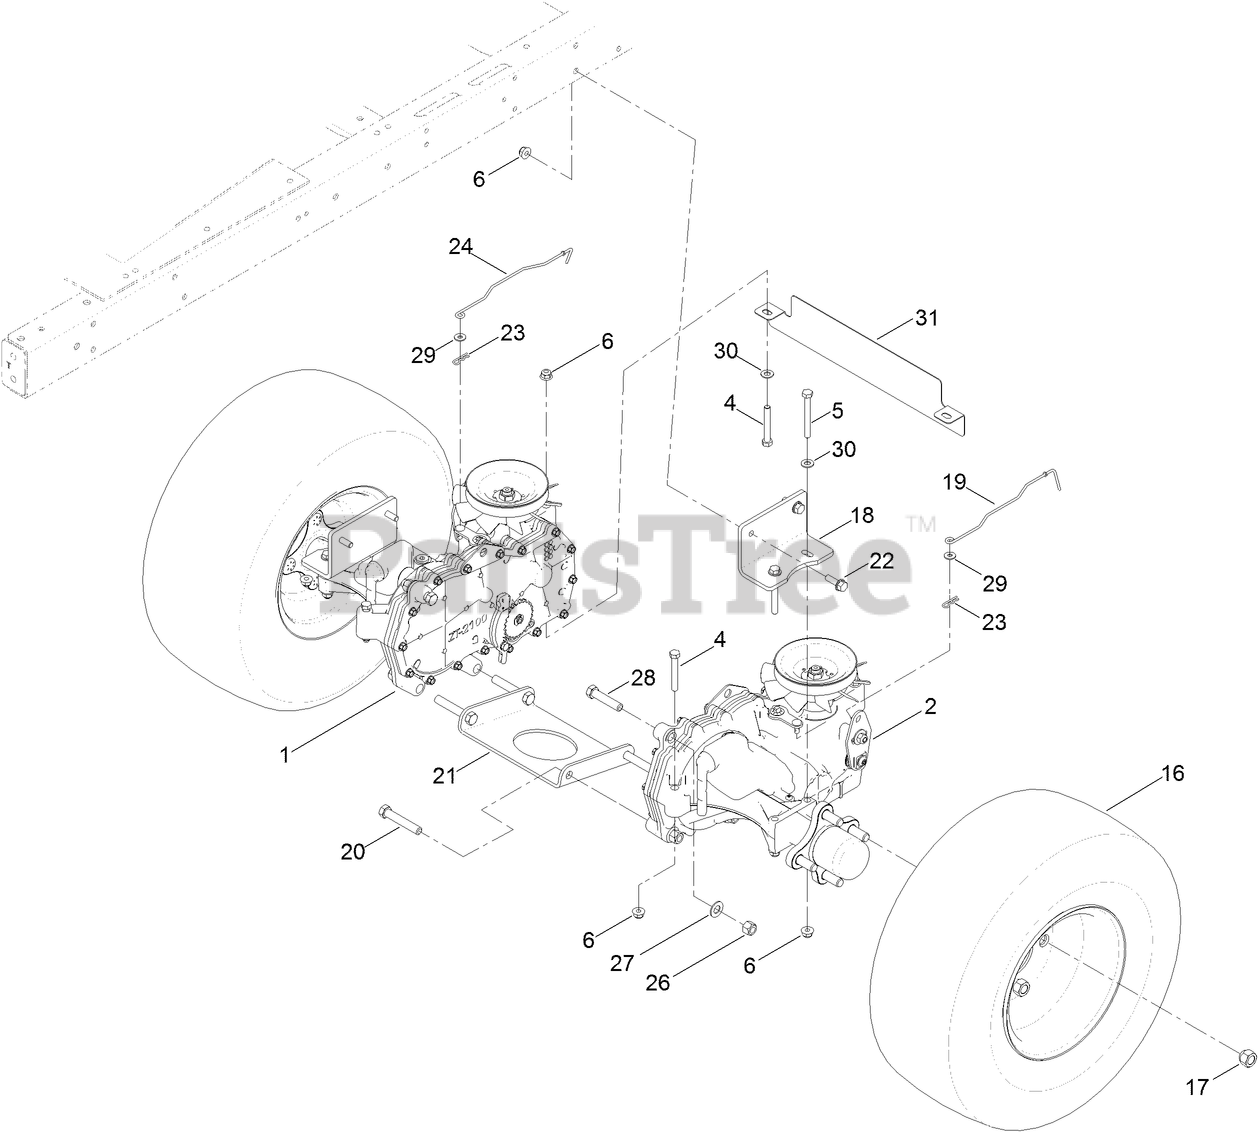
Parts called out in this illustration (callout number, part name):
1	RH HYDRO TRANSAXLE ASM
2	LH HYDRO TRANSAXLE ASM
4	SCREW-HH
5	SCREW-HH
6	NUT-HF, NI
16	2 PLY WHEEL AND TIRE ASM
17	NUT-LUG
18	MOUNT-HYDRO
19	ROD-BYPASS, LH
20	SCREW-HH
21	PLATE-CROSS, HYDRO
22	SCREW-HHF
24	ROD-BYPASS, RH
26	NUT-LOCK, NI
27	WASHER-FLAT
28	SCREW-HH
29	WASHER
30	WASHER-PLAIN
31	GUARD REAR, NARROW
